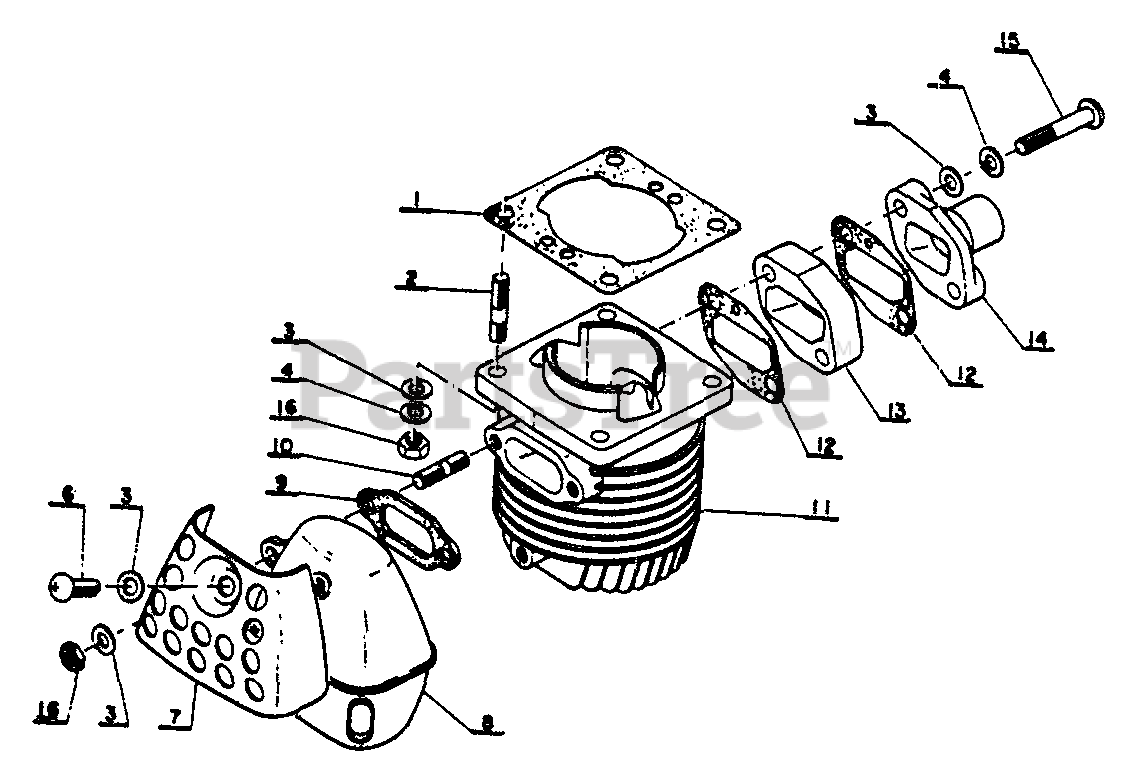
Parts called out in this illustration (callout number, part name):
1	Packing, cylinder
3	WASHER - 5
4	LOCKWASHER - 5
6	SCREW - 5X10
7	SHIELD, EXHAUST
8	MUFFLER
9	GASKET, EXHAUST
11	CYLINDER
12	GASKET, INTAKE
13	INSULATOR
14	PIPE, SUCTION
15	SCREW - 5X30
16	LOCKNUT
